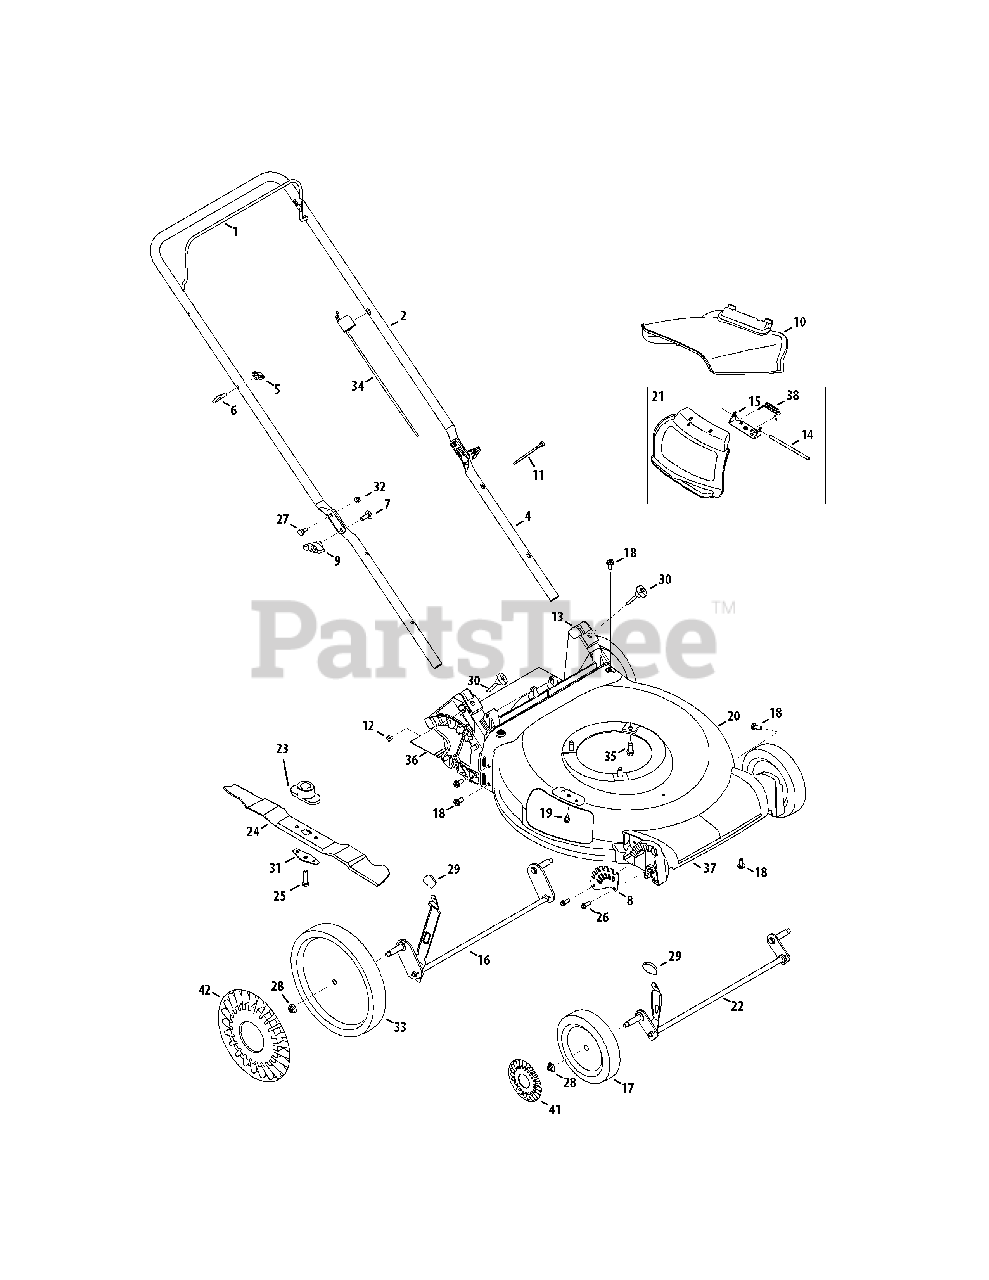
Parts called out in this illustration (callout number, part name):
1	Blade Control Handle - Black
2	Upper Handle - Black (adjustable)
4	Lower Handle
5	Knob 1/4-20
6	Rope Guide Bolt
7	Carriage Bolt 5/16-18
8	Front Height Adjustment Plate
9	Wing Knob 5/16-18 Black
10	Chute Deflector (w/clip)
11	Cable Tie
12	Sq. Nut 1/4-20
13	Rear Baffle
14	Hinge Pin
15	Chute Deflector Bracket
16	Rear Axle Ass’y - 11" wheel
17	Wheel Ass’y 7 x 2.0 Sleeve Zag Black
18	Hex Hd. Cap Scr. 5/16-14 x .75
19	Sems TT Scr. 1/4-20 x .50
20	21" Deck Ass’y
21	Hinged Mulch Plug Ass’y (Incl. ref. no.15, 38 & 14)
22	Front Axle Ass’y - 7 " wheel
23	Blade Adapter
24	21" Mulching Blade
25	Hex Bolt 3/8-24 x 1.5" Lg. (Gr 8)
26	Screw, 1/4-15 x .750
27	Shoulder Screw .375 x .126 x 1/4-20
28	Flange Locknut 3/8-16 Gr. F Nylon
29	Knob (Black)
30	Knob 1/4-20 x 1.73 Black
31	Blade Bell Support
32	Flanged Lock Nut 1/4-20 Gr. F Nylon
33	Wheel Ass’y 11 x 2 SL: Zag Black
34	Control Cable, 140 cc B&S
35	Hex Wash HD Tap Scr 3/8-16 x 1.0
36	Trailing Shield 4.54 x 17.37
37	Front Axle Cover
38	Torsion Spring
41	Hub Cap (11")
42	Hub Cap (7")
